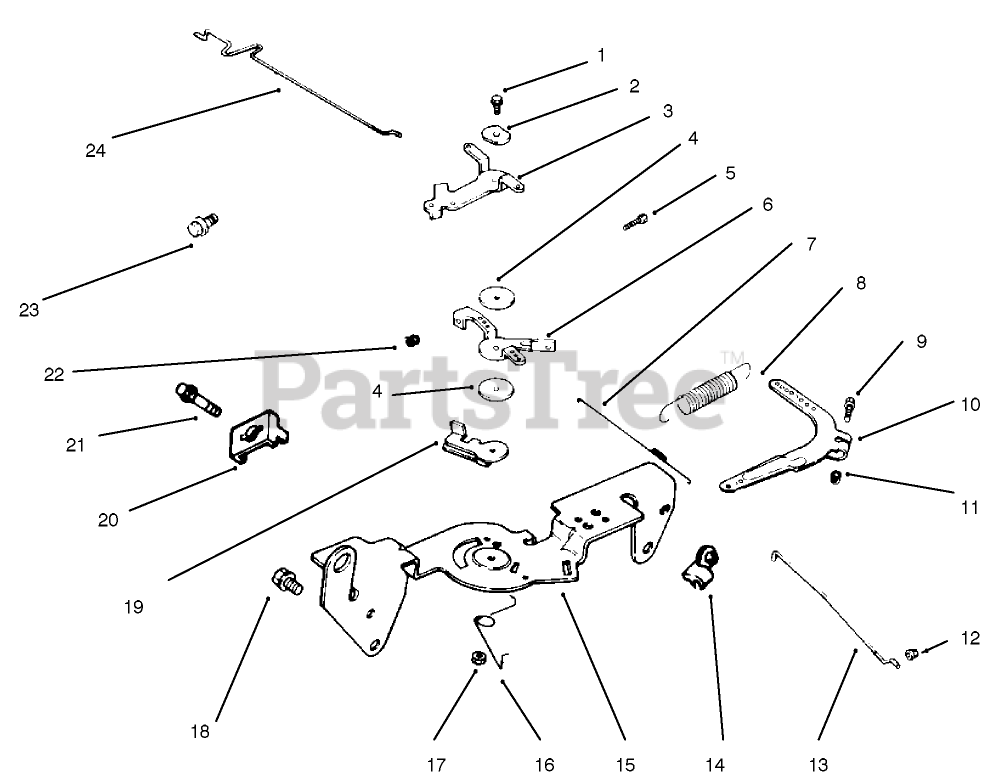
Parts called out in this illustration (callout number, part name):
1	Screw
2	Washer-Wave
2	Starter-Solenoid Shift (Incl. Ref. # 4-20)
3	Lever-Choke
3	Nut
4	Washer
4	Cap-Drive End
5	Nut
6	Lever-Throttle Control
6	Lever Starter Drive
7	Spring-Linkage
7	Washer
8	Spring-Governor
8	Nut
9	Screw
9	Ring-Retainer
10	Lever-Govenor
10	Solenoid
11	Nut
12	Bushing-Linkage
12	Drive Pinion
13	Linkage-Throttle
13	Armature
14	Bushing-Linkage
14	Frame
15	Bracket-Control
15	Kit-Brush (Incl. Ref. # 16)
16	Spring-Choke Return
16	Spring Brush
17	Nut
17	Holder-Brush
18	Screw
18	Insulator
19	Lever-Actuator, Throttle
19	Cap-Commutator End
20	Clamp
20	Bolt
21	Screw
22	Nut
23	Screw
24	Linkage-Choke
